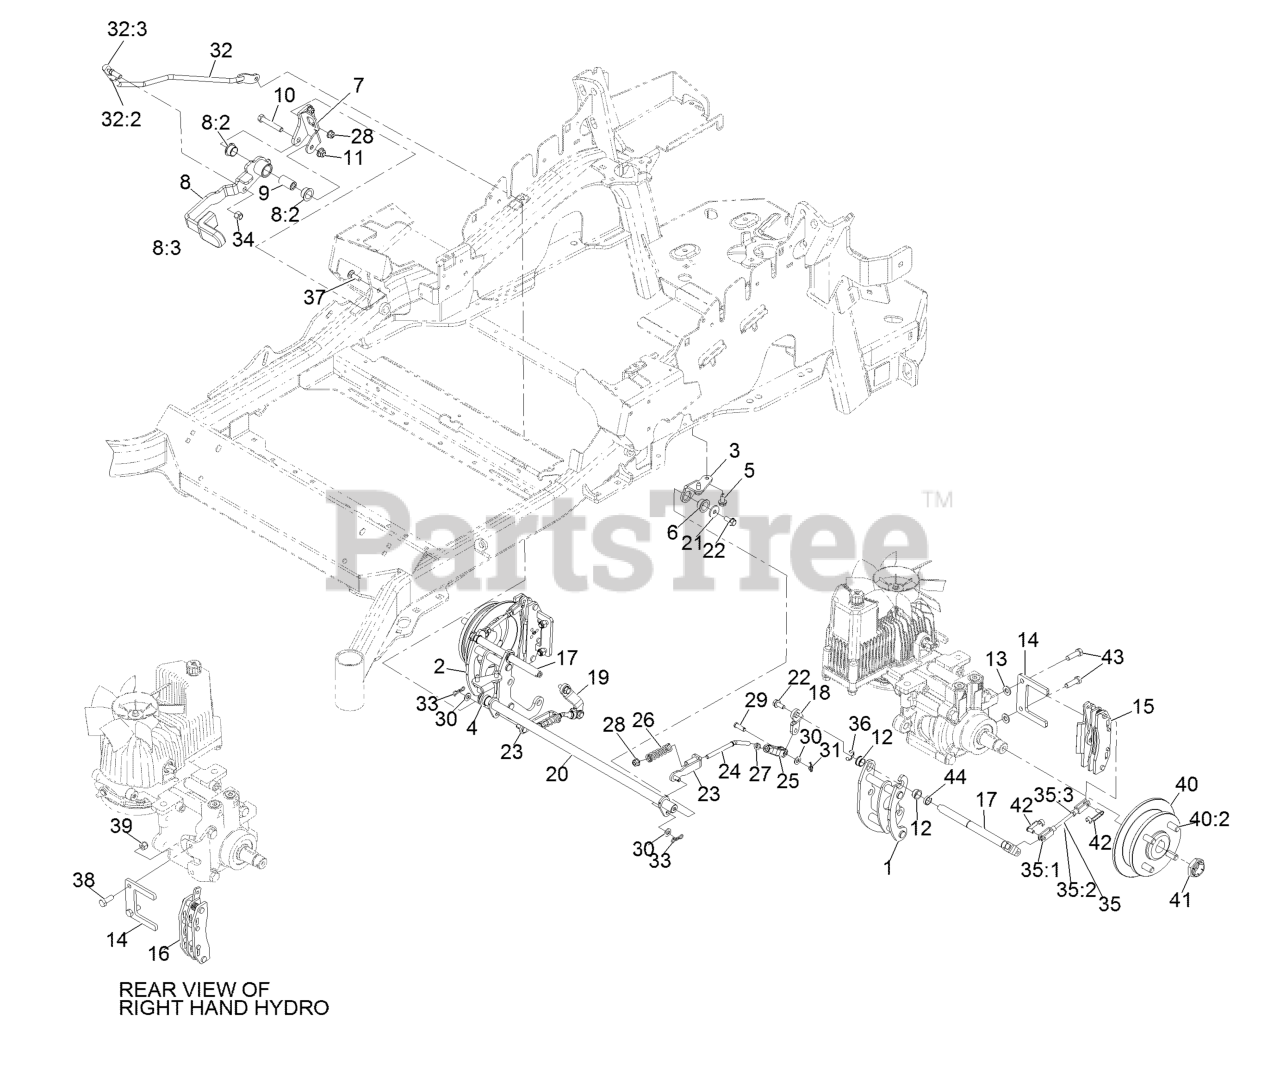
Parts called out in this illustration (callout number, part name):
1	Mount-Bellcrank, LH
2	Mount-Bellcrank, RH
3	Mount-Pivot, LH
4	Mount-Pivot, RH
5	Screw-HWH 5/16-18 X 3/4 Tf
6	Bushing-Flanged
7	Bracket-Mount
8	Brake Lever ASM W/ Grip
8:2	Bushing-Flanged
8:3	Grip-Lever
9	Handle-Pivot, Brake
10	Screw-HH 3/8-16 X 2 1/4
11	Nut-Nyloc 3/8-16 Flg
12	Bushing
13	Washer-3/8 SAE
14	Plate-Mount, Brake
15	Caliper-Brake
16	Caliper-Brake, RH
17	Bellcrank
18	Arm-Inner, LH
19	Arm-Inner, RH
20	Shaft-Cross
21	Washer-Flat
23	Bracket-L
24	Linkage-Mid
25	Yoke-Offset
26	Spring-Compression
27	Nut-Jam 5/16-24
28	Nut-Nyloc 5/16-18 Flg
29	Pin-Clevis 5/16 X 1 49/64
30	Washer-5/16 SAE
31	Pin-Cotter, Locking
32	Front Linkage ASM
32:2	End-Tie Rod, RH
32:3	Nut-Jam 3/8-24
33	Pin-Cotter, Locking
34	Nut-Nyloc 3/8-24
35	Rear Linkage ASM
35:1	Yoke
35:2	Linkage, Rear
35:3	Nut-Jam 1/4-28
37	Bolt-Carriage 5/16-18 X 1
38	Screw-HH 3/8-16 X 1
39	Nut-Nyloc 3/8-16
40	Wheel Hub ASM
40:2	Stud-Wheel
41	Locknut
42	Pin-Clevis, Spring
43	Screw-HH 3/8-16 X 1 1/4 Patch Lock
